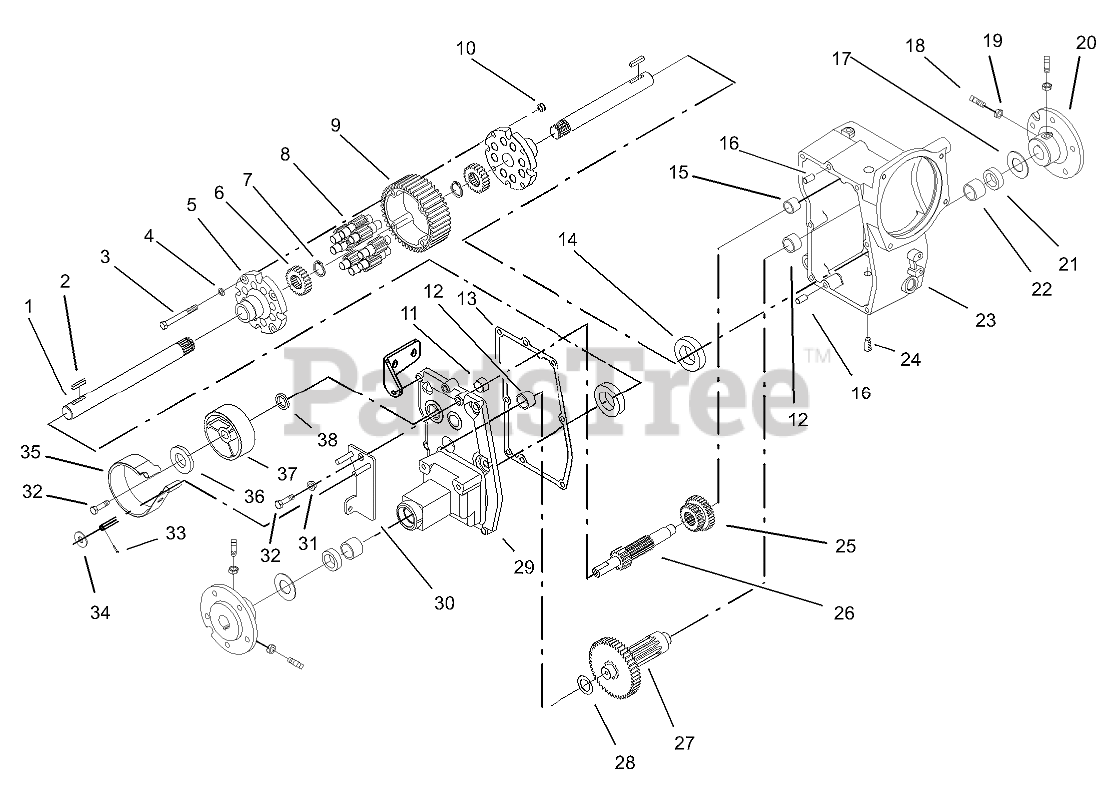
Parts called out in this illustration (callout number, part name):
1	AXLE-REAR
3	BOLT-HEX
4	WASHER
5	END CAP-DIFFERENTIAL
6	GEAR-AXLE DIFFERENTIAL
7	RING-SNAP
8	GEAR-PINION, 11T
9	GEAR-DIFFERENTIAL RING, 43T
11	BEARING-NEEDLE
12	BEARING-NEEDLE
13	GASKET-CASE
14	BEARING-BALL
15	BEARING-NEEDLE
16	PIN-LOCATING
17	WASHER-THRUST
18	SCREW-SET, SQH
19	NUT-JAM
20	HUB-WHEEL
21	SEAL-OIL
22	BEARING
23	CASE-LH
24	PLUG-PIPE
25	GEAR-SLIDING
26	SHAFT-BRAKE
27	GEAR ASM
28	WASHER-THRUST
29	CASE-RH
30	Arm-PIVOT, Brake
31	CAM-SPACER
32	SCREW-HH, LOCK
33	PIN-COTTER
34	WASHER-FLAT
35	BAND-BRAKE
36	WASHER
37	DRUM-BRAKE
38	SEAL-OIL
